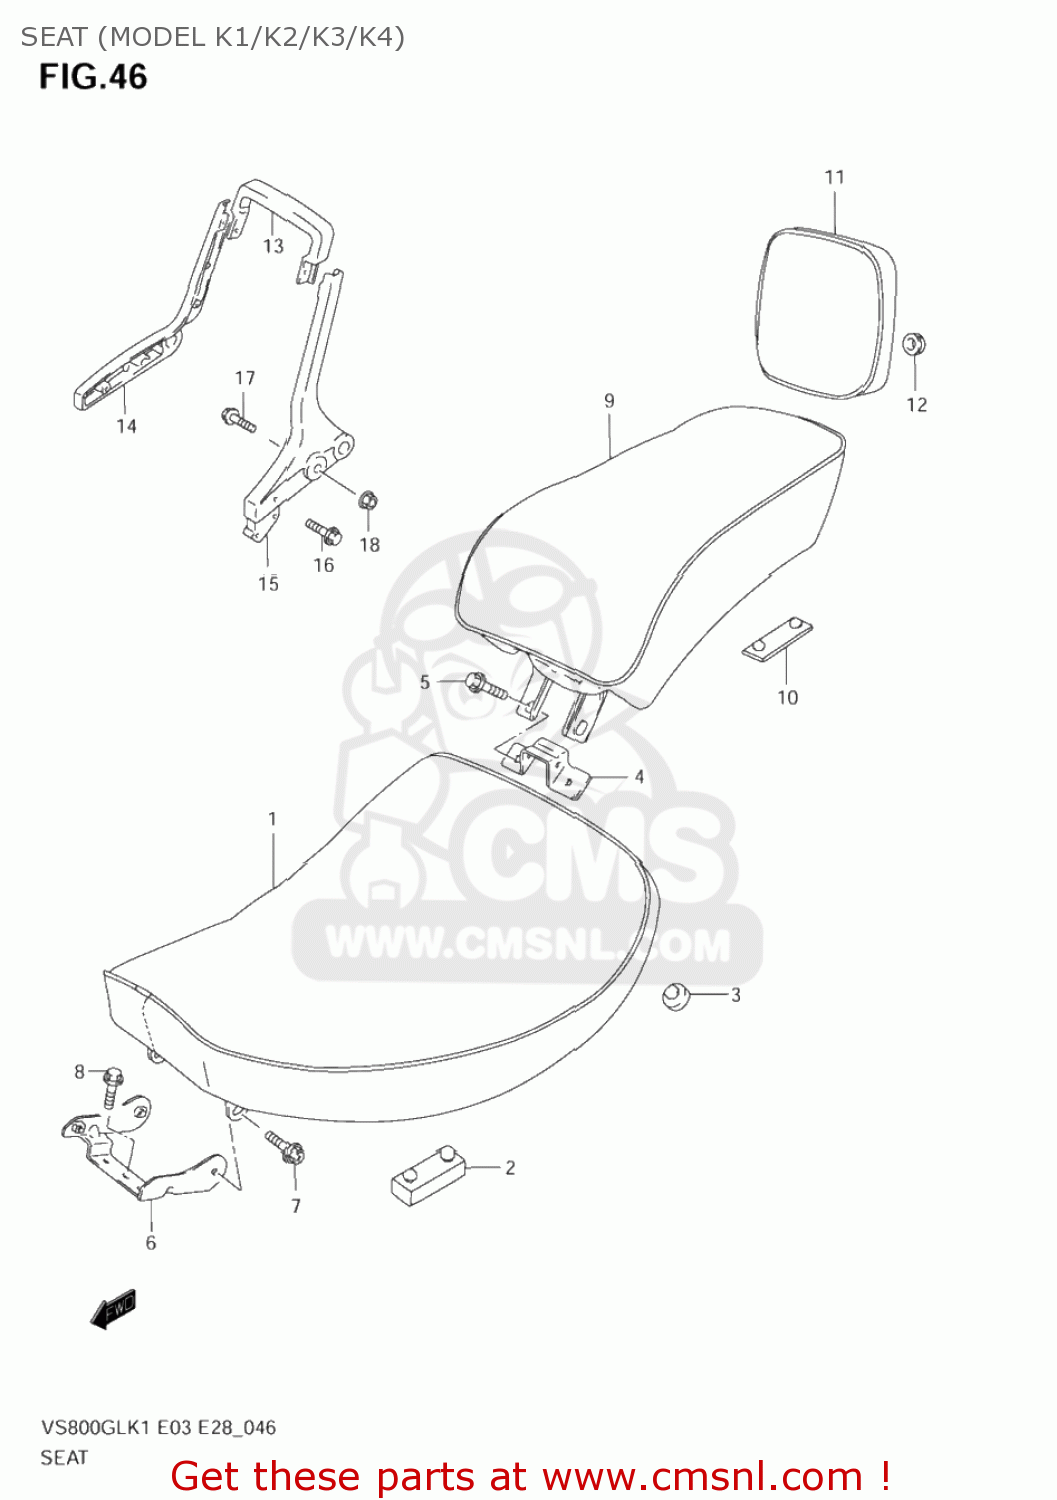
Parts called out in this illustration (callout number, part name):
1	SEAT ASSY
2	CUSHION,SEAT
3	CUSHION
4	PLATE,FR SEAT HOOK & RR
5	BOLT(6X16)
6	BRACKET,SEAT FR
7	BOLT(6X16)
8	BOLT
9	SEAT ASSY,PILLION
10	CUSHION
11	PAD ASSY,SEAT
12	CUSHION
13	HANDLE,PILLION RIDER UPR
14	HANDLE,PILLION RIDER,R
15	HANDLE,PILLION RIDER
16	BOLT
17	BOLT
18	NUT
